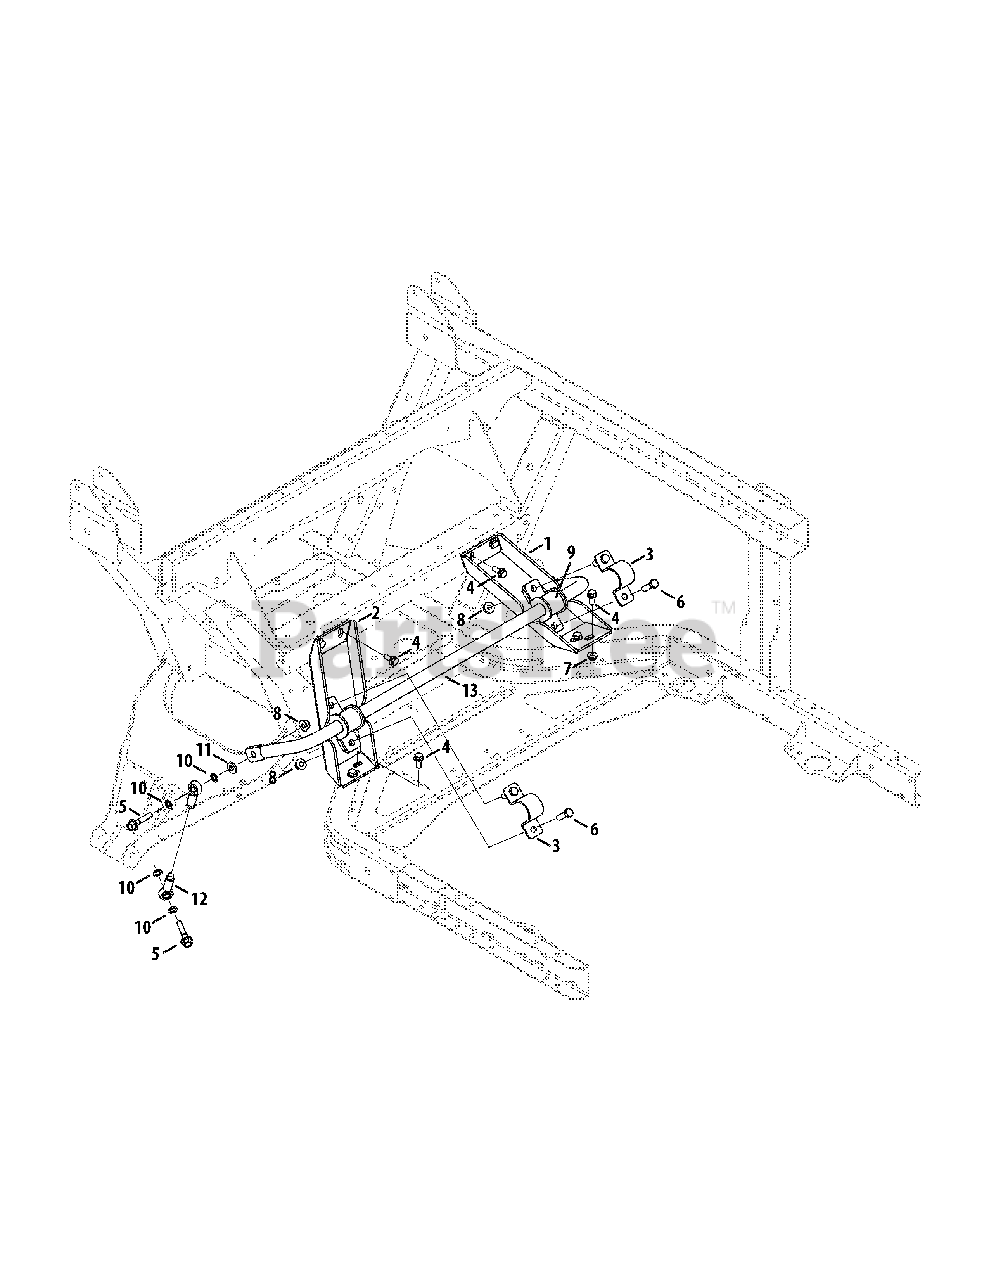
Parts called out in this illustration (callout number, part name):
1	Sway Bar Assembly, LH
2	Sway Bar Assembly, RH
3	Sway Bar Mount
4	Screw, 5/16-18
5	Hex Cap Screw, 3/8-16 x 1.75
6	Hex Cap Screw, 3/8-16 x 1.25
7	Nut, 5/16-18, Flange Lock
8	Nut, 3/8-16, Flange Lock
9	Bushing, Sway Bar
10	Washer, .385 x .62 x .063
11	Washer, .407 x .812 x .135
12	Control Rod, .375 x 3.886
